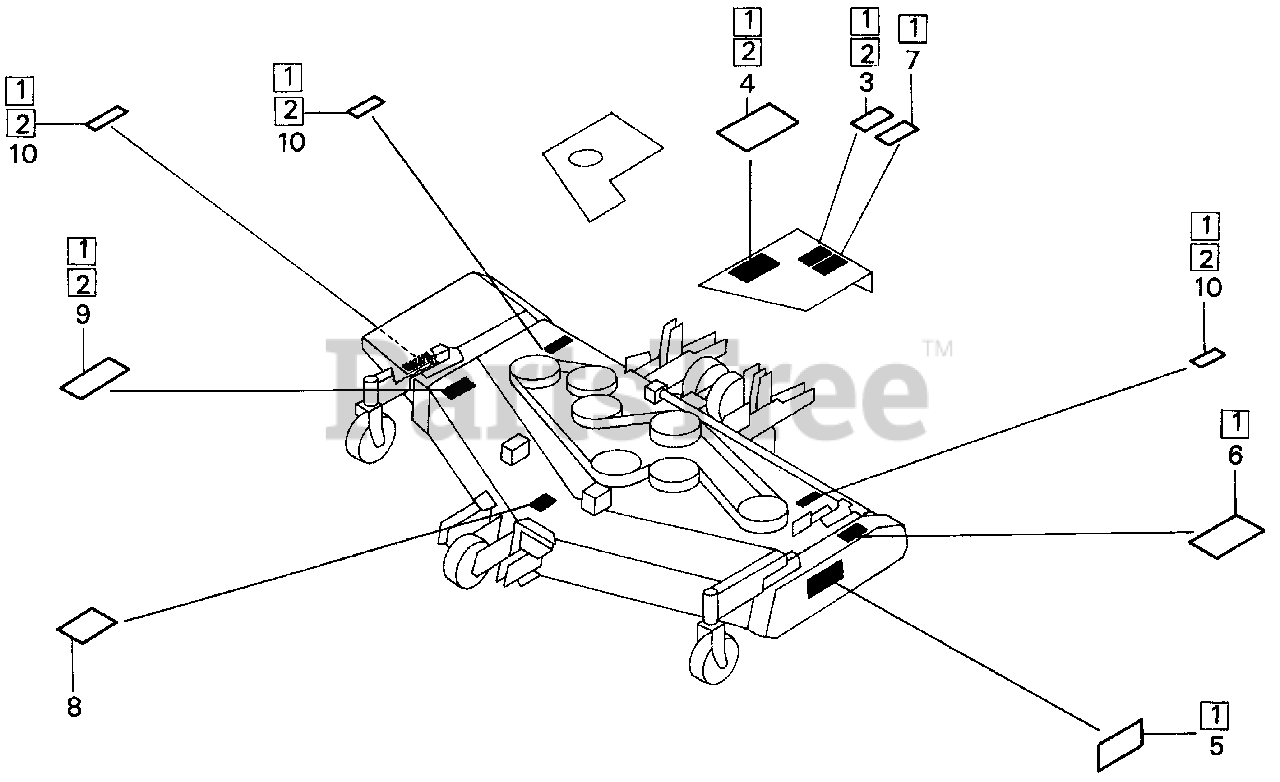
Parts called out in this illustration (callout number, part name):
2	MARK SET, SAFETY
3	LABEL B, WARNING (ENGLISH)
4	LABEL A, WARNING (ENGLISH)
5	MARK SET, SAFETY
6	MARK SET, SAFETY
7	MARK SET, SAFETY
8	MARK SET, SAFETY
9	LABEL A, DANGER (ENGLISH)
10	LABEL B, DANGER (ENGLISH)
